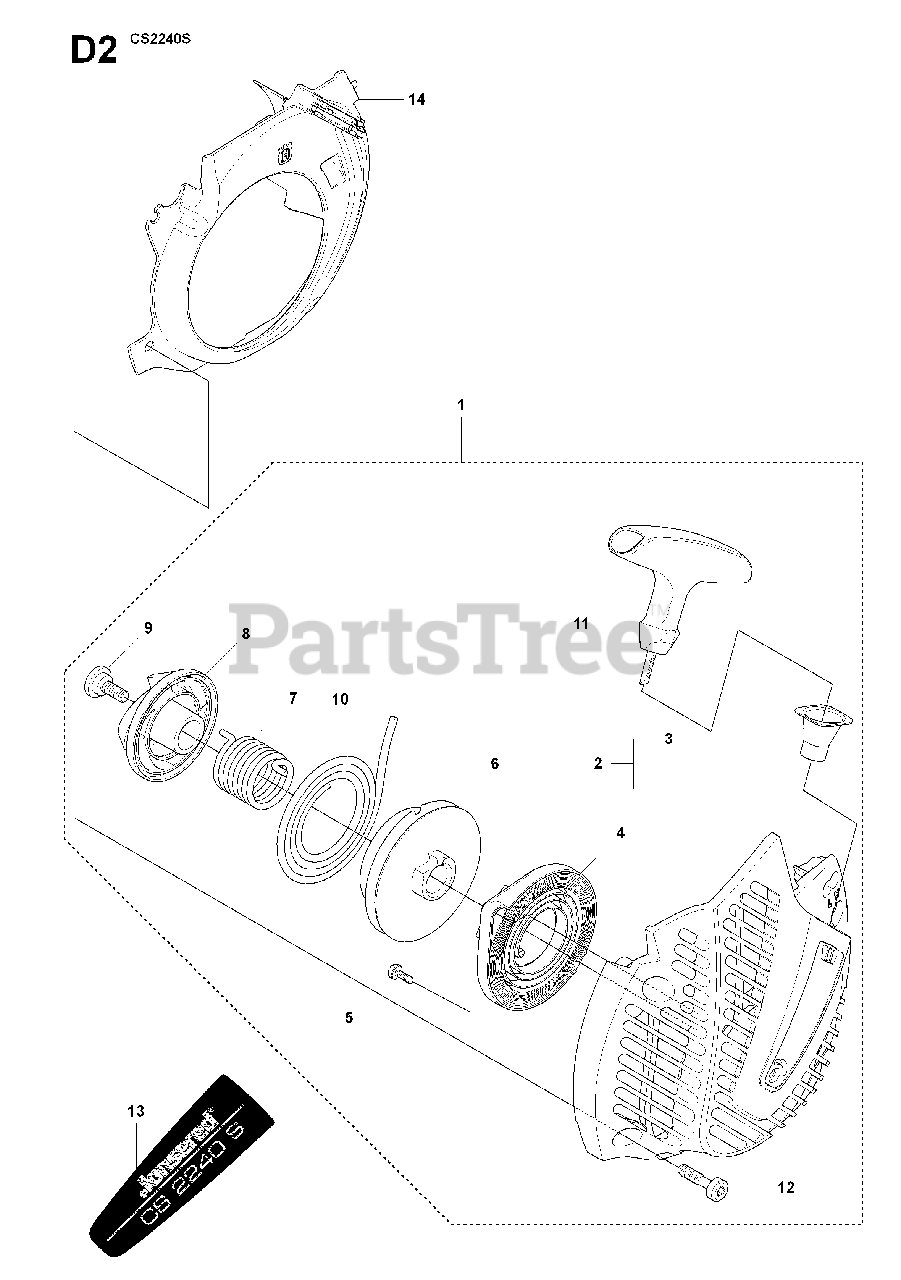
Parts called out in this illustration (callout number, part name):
1	STARTER
2	STARTER HOUSING
4	SPRING CASSETTE ASSY
5	SCREW
6	STARTER PULLEY
7	SPRING
8	CARRIER
9	SCREW
10	STARTER ROPE
11	STARTER HANDLE
12	SCREW
14	%COOLING AIR CONDUCTOR
